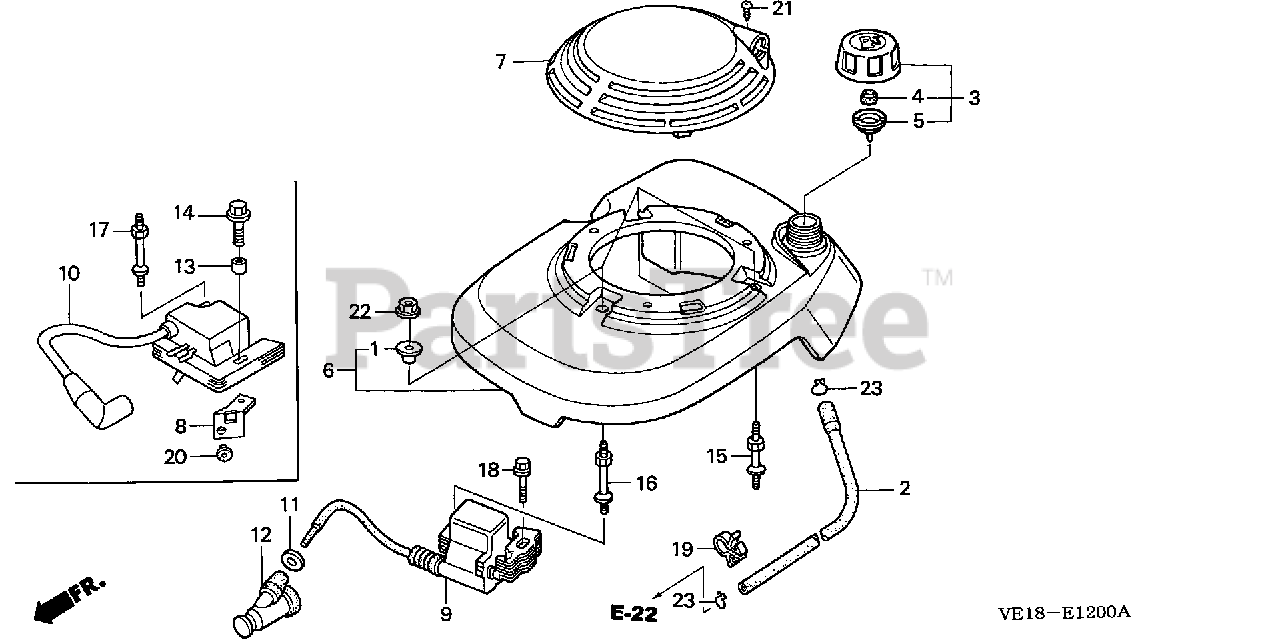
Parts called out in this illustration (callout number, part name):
1	COLLAR, AIR CLEANER (TOYO ROKI)
2	TUBE, FUEL TANK (135MM)
3	CAP ASSY., FUEL TANK
4	SPONGE, FUEL CAP BREATHER
5	GASKET, FUEL CAP
6	COVER, FAN
7	HOOD, FAN COVER *R8* (SMOOTH) (BRIGHT RED)
9	COIL ASSY., IGNITION
11	GROMMET, IGNITION WIRE
12	CAP ASSY., NOISE SUPPRESSOR
15	BOLT A, STUD
16	BOLT B, STUD
18	BOLT, FLANGE (6X25) (CT200)
19	CLIP B, CABLE (9MM BLACK)
21	SCREW, TAPPING (4X20)
22	NUT, FLANGE (6MM)
23	CLIP, TUBE (B10)
